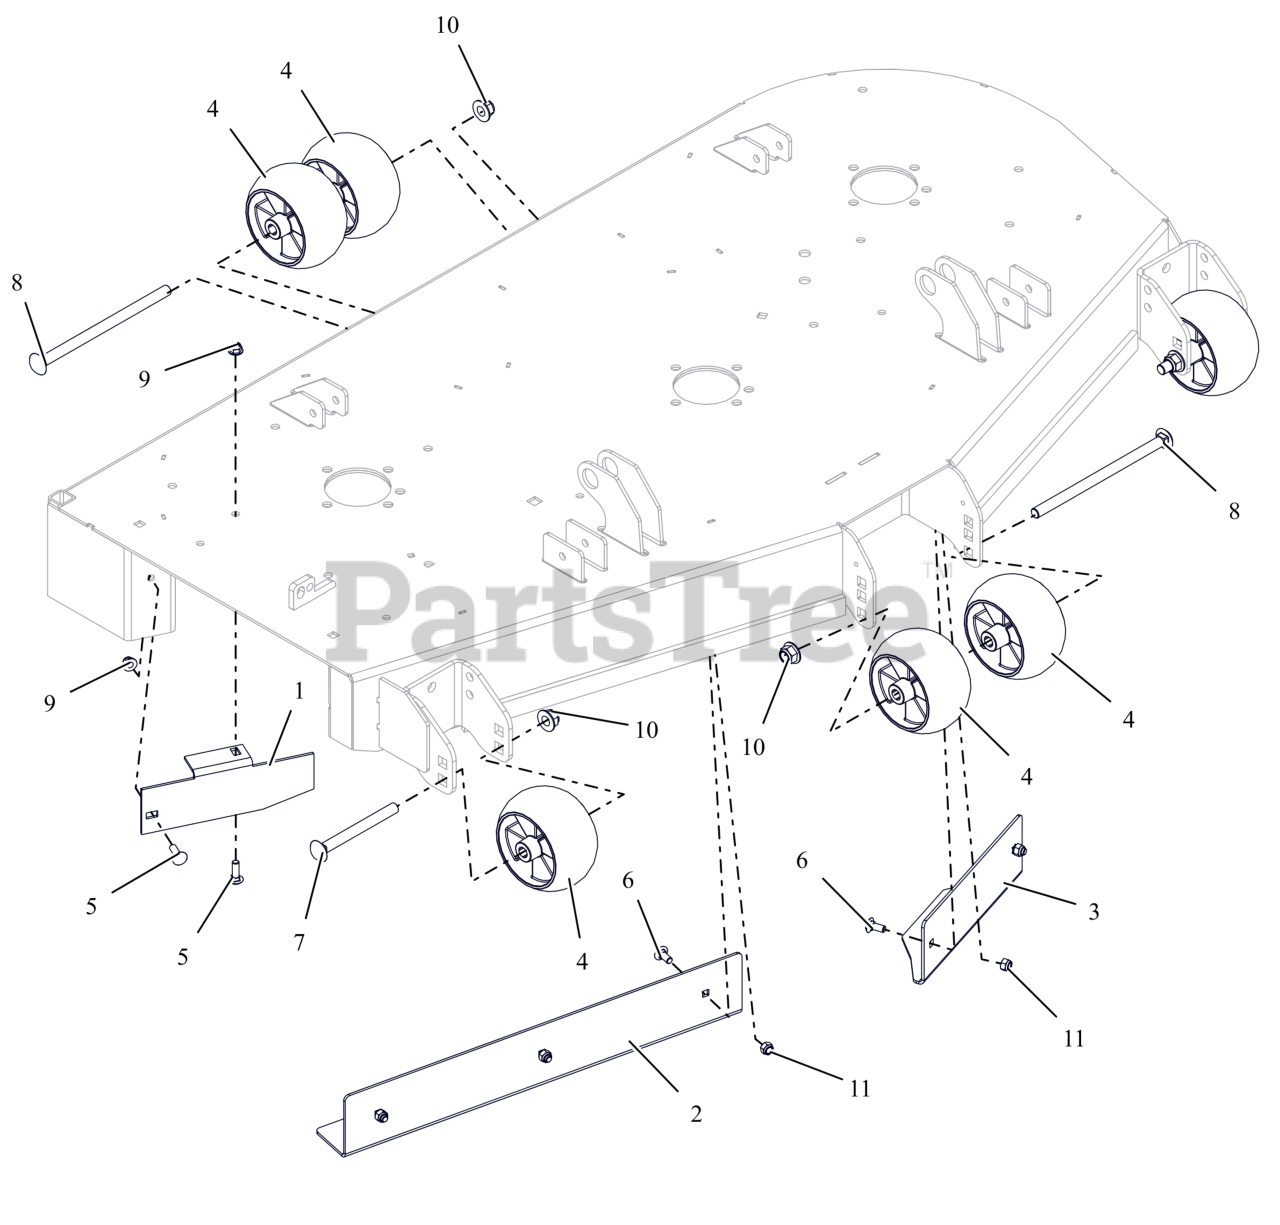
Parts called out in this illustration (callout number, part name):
1	BAFFLE, DISCHARGE, 52"
2	BAFFLE, 52" RH VACUUM (RED)
3	BAFFLE, 52" LH VACUUM (RED)
4	WHEEL, ANTI SCALP - 5X3 CTR W/RIBS
5	BLT,RHSN .31-18X1.00 G5 ZCC
6	BLT,RHSN .31-18X.75 G5 ZCC
7	BLT, RHSN .50-13X5.00 G5 ZCC
8	BTL,RHSN .500-13 X 8.5S G5 ZCC
9	NUT,NYL-FLG .31-18 GF ZCC
10	NUT,NYL-FLG .50-13 GF ZCC
11	NUT,NYL .31-18 G5 ZCC
